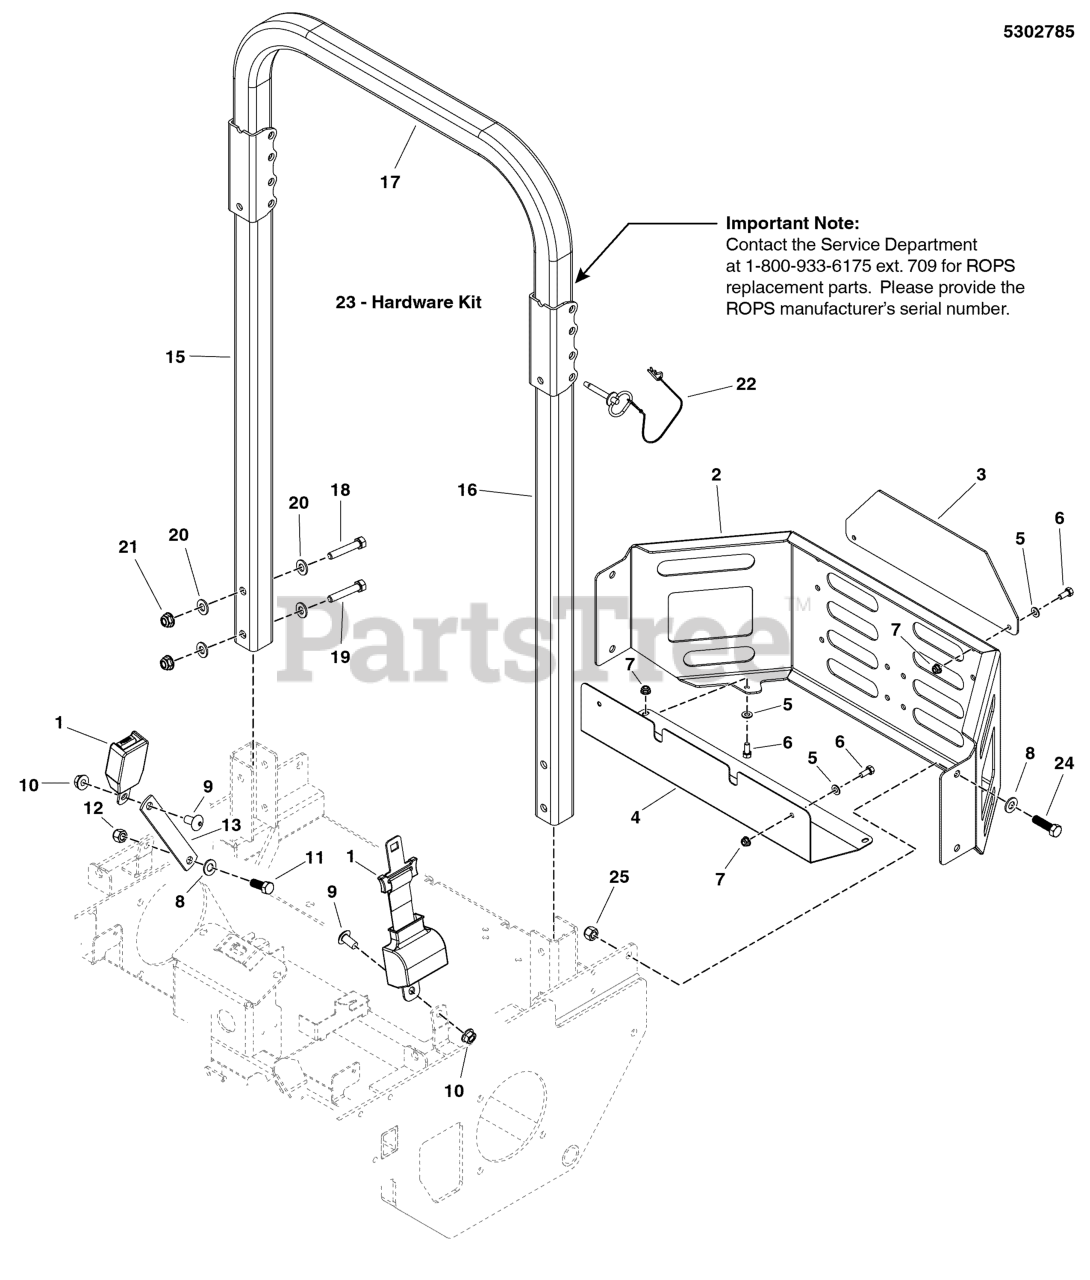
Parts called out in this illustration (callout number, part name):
1	SEAT BELT, RETRACTING - ASSM
3	PLATE, REAR BUMPER, 61 SNP - SNP RED
5	WASHER, 5/16" SAE
6	BOLT, 5/16-18 X 3/4 GD5
7	NUT, 5/16-18 HEX NYLOCK FLANGE
8	WASHER, 1/2 SAE
9	SCREW, 1/2-13 X 1.00, SHCS
10	NUT, Hex Flange, Nylock, 1/2-13
11	BOLT, 1/2-13 X 1-1/4 GD5 CZ
12	NUT, 1/2-13 HEX NYLON LOCK
13	PLATE, SEAT BELT ANCHOR - BLK
14	ROPS (Call 1-800-933-6175 ext. 2193 if replacing a ROPS)
15	ROLL BAR POST, RH (SV)
16	ROLL BAR POST, LH (SV)
17	ROLL BAR TOP LOOP (SV)
18	BOLT, 1/2-13 X 3-1/4, HEX HD, GD5, CZ (SV)
19	BOLT, 1/2-13 X 3-1/2, HEX HD, GD5, CZ (SV)
20	WASHER, 1/2 SAE
21	NUT, Hex Flange, Nylock, 1/2-13
22	PIN, HITCH, .50 X 3.25 W/ LAY (SV)
23	HARDWARE KIT, ROPS (SV)
24	BOLT, 1/2-13 X 1-1/2 GD5 CZ
25	NUT, Hex Flange, Nylock, 1/2-13
